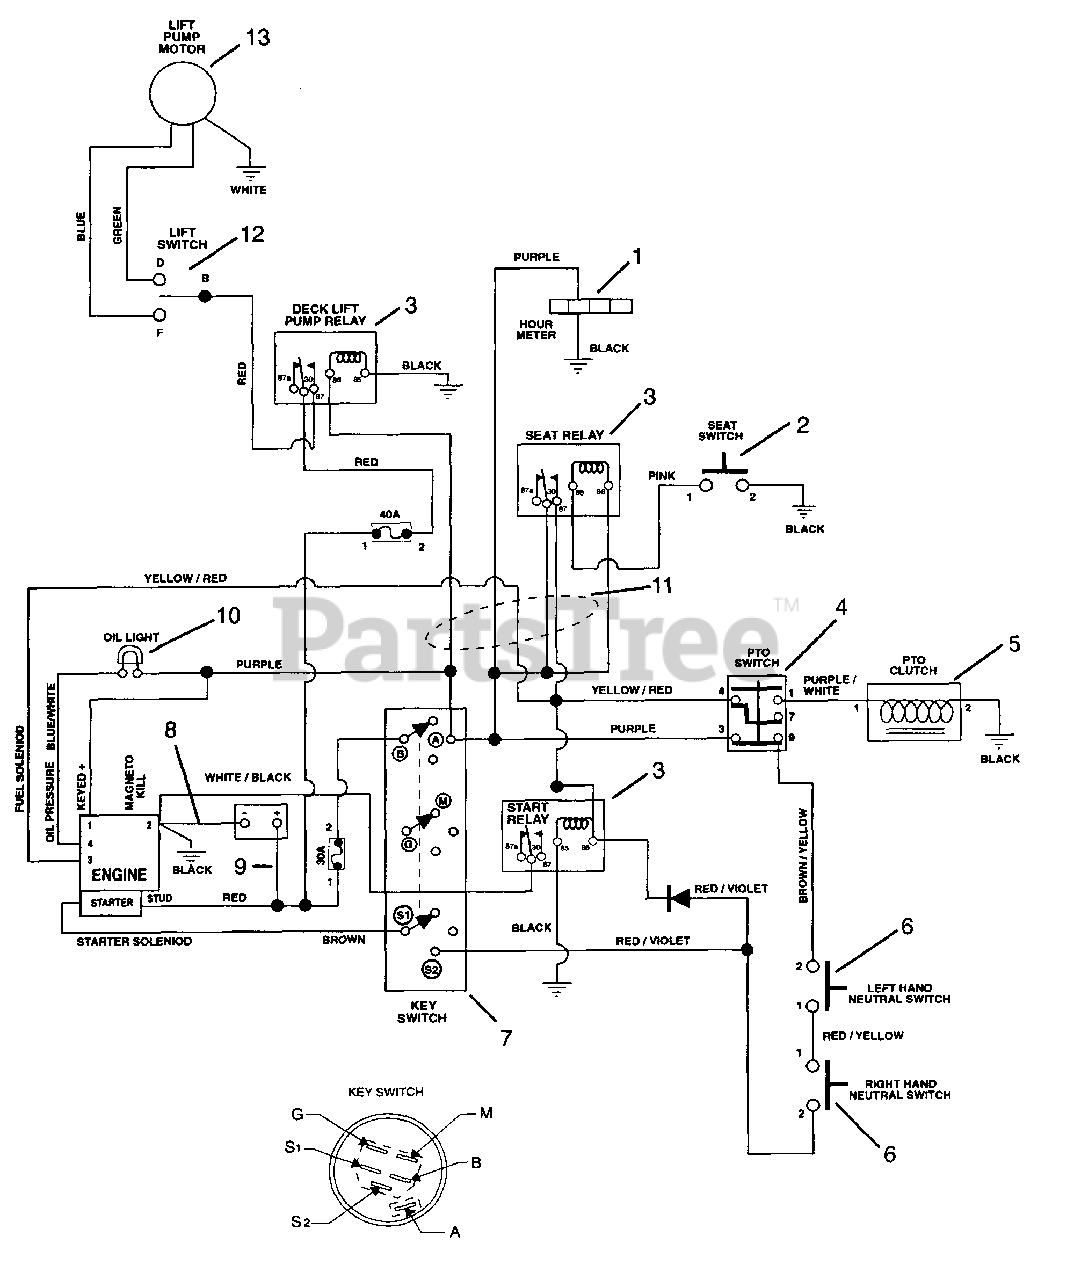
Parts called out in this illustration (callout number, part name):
1	Hour Meter
2	Switch - Seat
3	Relay
4	Switch, Clutch with Retainer Ring
5	Clutch, Electric - Warner
6	Switch - Neutral Start N.O.
7	Key Switch
8	Start Cable 22"
9	Cable, Negative Battery
10	Light, Indicator
11	Harness, Wiring 18 HP Kohler
12	Switch Assembly
13	Pump, Electric Hydraulic
